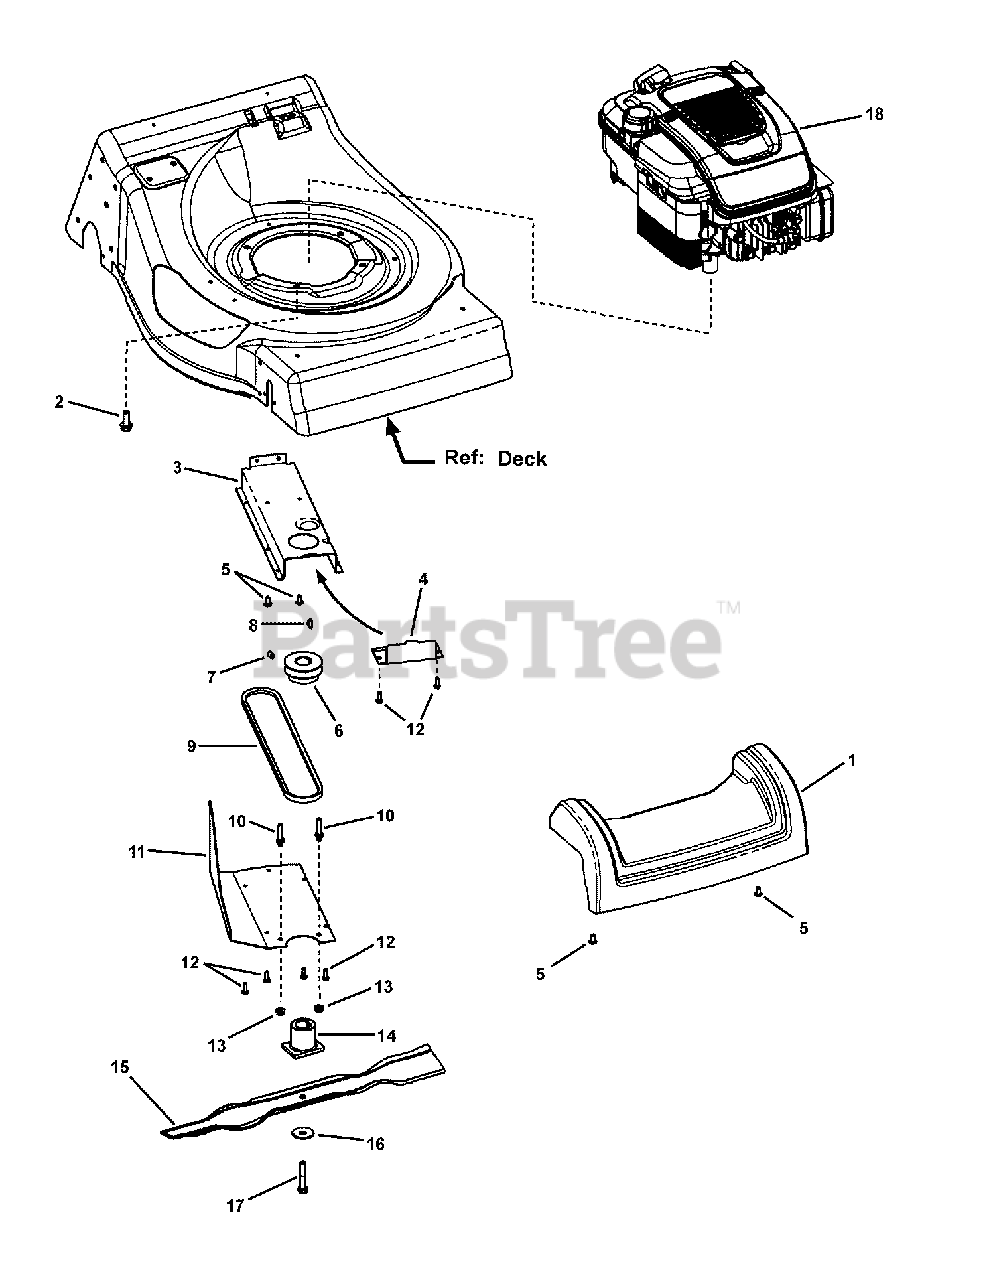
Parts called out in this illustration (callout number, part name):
1	COVER, Front, 21" WBM, RD
2	SCREW, 3/8-16 x 1" Hex Washer Self-Tap
3	BELT GUARD
4	COVER, Belt
5	SCREW, 1/4-20 x 1/2" Pan Head Self-Tap, Torx
6	PULLEY, Engine
7	SET SCREW, 5/16-18 x 1/2" Hex Recess
8	KEY, #HP-506 Hi-Pro
9	BELT, 3L, Traction Drive, 21" Pivot Handle
10	BELT GUIDE, Engine, 21" RD
11	COVER, Belt Guard
12	SCREW, #10 x 1/2", AB, w/Washer
13	NUT, 1/4-20 Hex Flange Lock, GR 5, YZ
14	HUB, Blade, 21" WBM, RD, 2 Position
15	BLADE, Wave, 21" Steel Deck
16	WASHER, Cone
17	SCREW, 3/8-24 x 2" Hex Head Cap, GR 5
18	* ENGINE, B&S, 675 Ser B3, X-Spec
18	* ENGINE, B&S, 675 Ser, X-Spec, F3
18	* ENGINE, B&S, 700 Ser, B3, X-Spec
18	* ENGINE, B&S, 700 Ser, X-Spec
